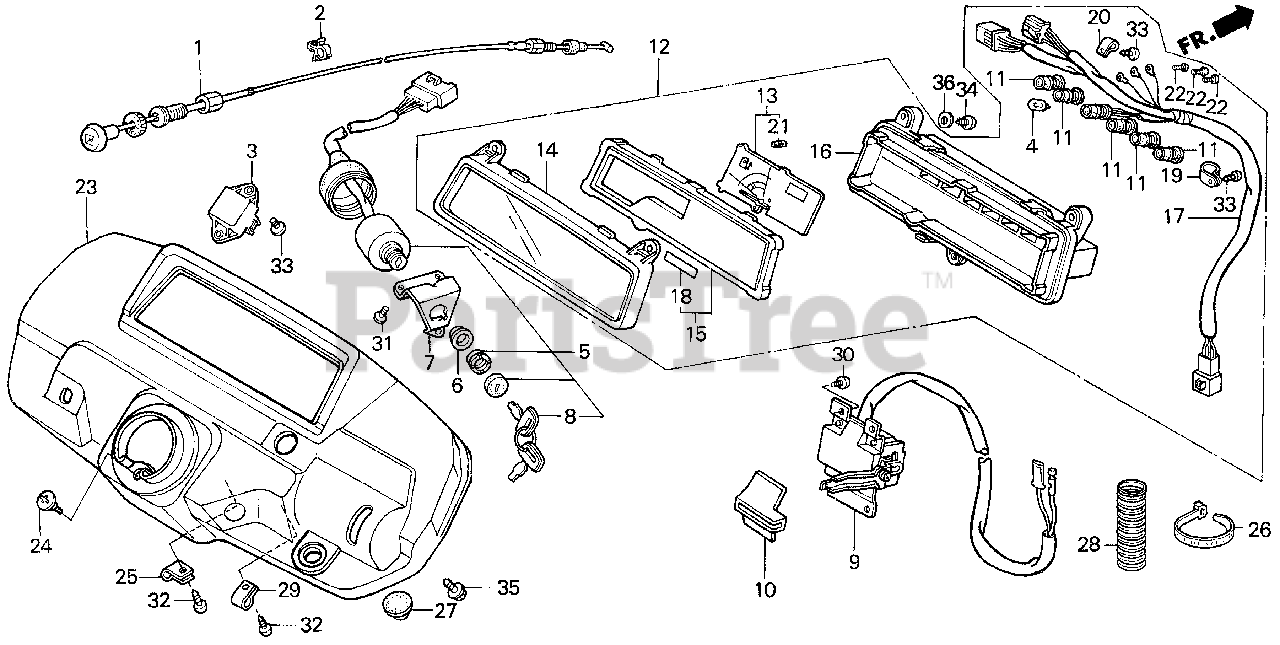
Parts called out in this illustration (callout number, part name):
1	CABLE, CHOKE
2	CLIP, IGNITION WIRE (8MM)
3	ALARM UNIT, OIL
4	BULB, WEDGE BASE (12V 1.7W) (STANLEY)
5	SWITCH ASSY., COMBINATION
6	COLLAR, COMBINATION SWITCH
7	BASE, COMBINATION SWITCH
8	KEY ASSY., COMBINATION SWITCH
9	SWITCH ASSY., HEADLIGHT
10	KNOB, TURN SIGNAL SWITCH
12	METER ASSY., FUEL
13	METER, FUEL
15	PLATE, REFLECTING
18	MARK, EMBLEM (E)
21	RUBBER, CUSHION
22	SCREW-WASHER (3X22)
23	PANEL, INSTRUMENT *NH105* (MAT BLACK)
24	SCREW, METER VISOR SETTING
25	CLIP (14MM)
26	BAND, CABLE (120MM) (BLACK)
27	PLUG, INSTRUMENT PANEL
28	TUBE, CORRUGATED (22X100)
29	CLIP, WIRE HARNESS (6.3MM)
30	SCREW, TAPPING (4X10)
31	SCREW, TAPPING (4X10)
32	SCREW, TAPPING (4X10)
33	SCREW, TAPPING (4X16)
34	SCREW, TAPPING (6X25)
35	SCREW, TAPPING (6X16)
36	WASHER, PLAIN (6MM)
